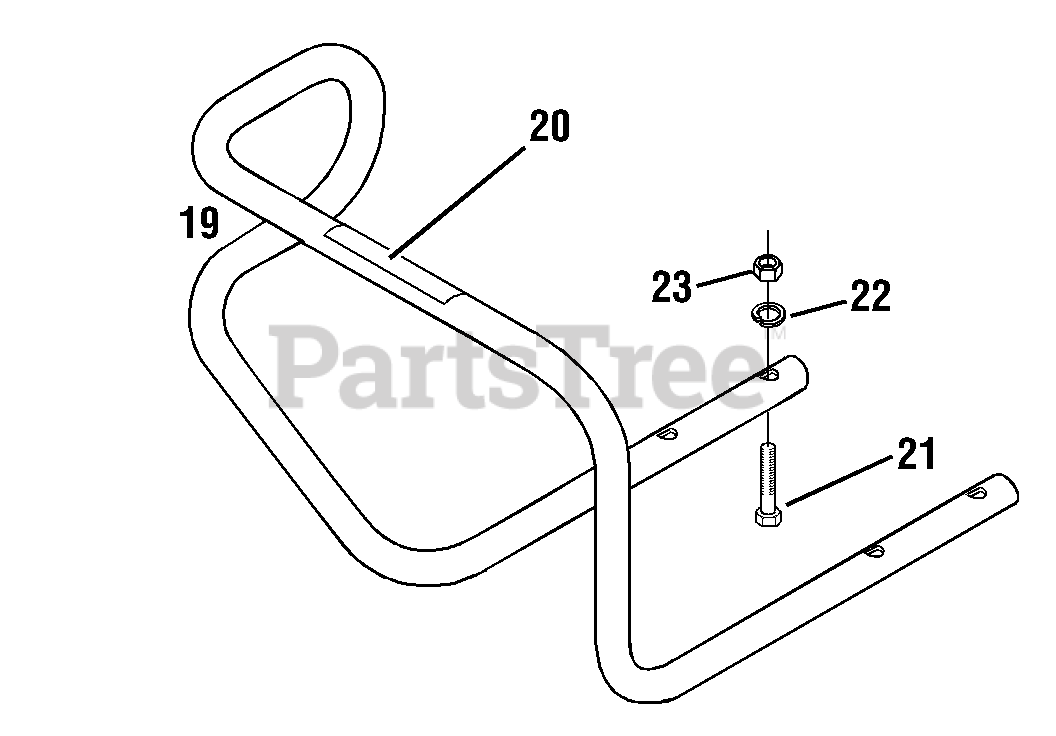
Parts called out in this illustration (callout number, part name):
19	Bumper
20	Decal - Caution
21	Screw-hex hd., 5/16-18 x 2-1/4
22	Lockwasher-5/16
23	Nut-hex, 5/16-18
